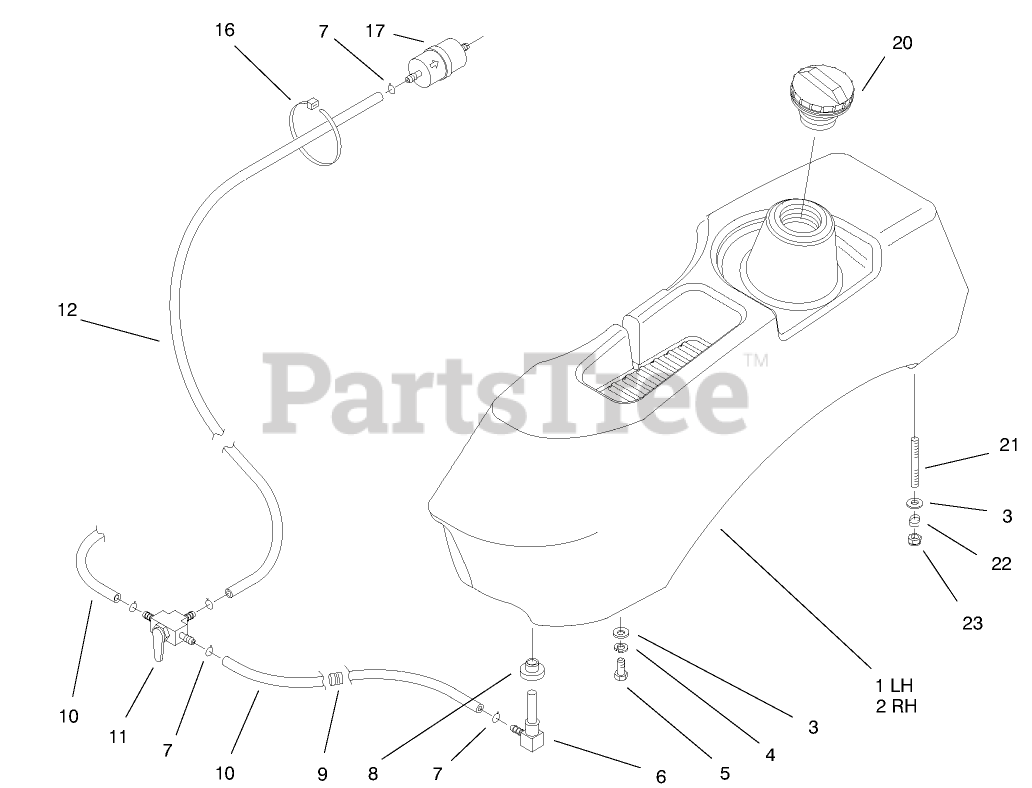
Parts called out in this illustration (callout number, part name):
1	TANK-FUEL, LH
2	TANK-FUEL, RH
3	WASHER-PLAIN
4	WASHER-LOCK
5	SCREW-HH
6	Elbow
7	Clamp
8	Bushing
9	Grommet-Fuel Line
10	Fuel Line
11	Valve-Fuel Line
12	Fuel Line
16	Tie-Plastic
17	Filter-Fuel
20	CAP-FUEL
21	Stud
22	Spring-Fuel Tank
23	Nut-Lock
